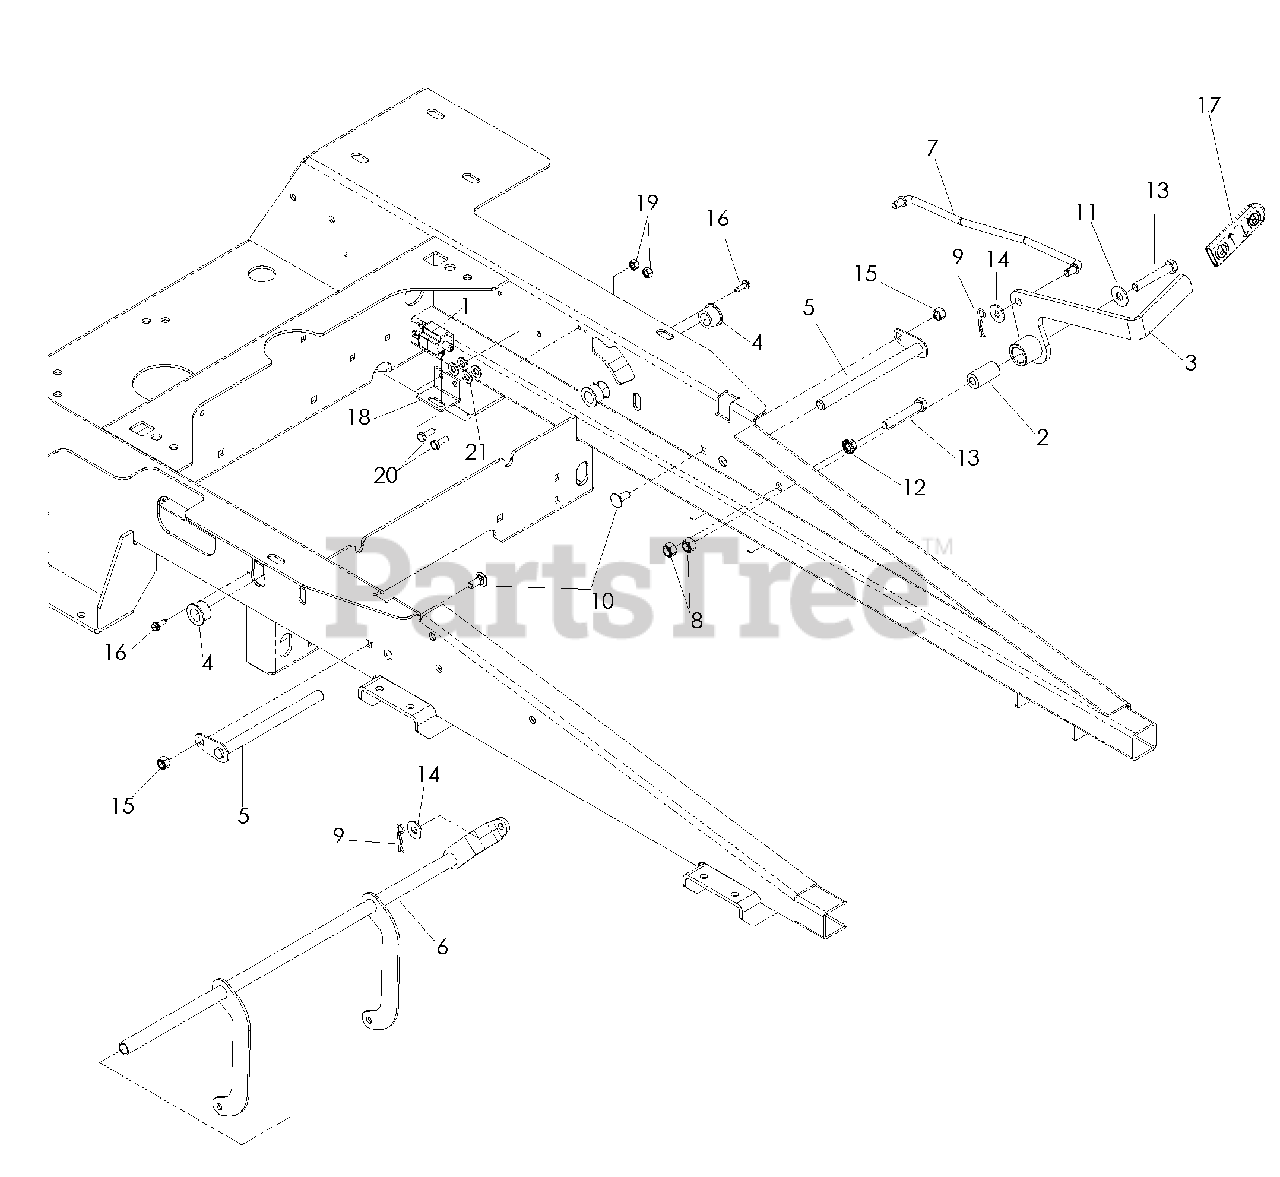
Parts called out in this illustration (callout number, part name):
1	SWITCH, INTERLOCK
3	BRAKE LEVER
4	BUSHING, PLASTIC
5	PIVOT SHAFT
6	BRAKE SHAFT
8	NUT 3/8-16 NYLOC
9	PIN, HAIR .073 x 17/16
10	RHSNB 5/16-18 x 3/4
11	WASHER 3/8
12	NUT 3/8-16 WHIZLK
13	HCS 3/8-16 x 2 1/4
14	WASHER 5/16
15	NUT 5/16-18 NYLOC
16	SCREW #10-24 x 5/8 WSH HD
17	GRIP, PARK BRAKE
18	BRACKET, BRAKE SWITCH
19	NUT 1/4-20 NYLOC
20	HCS 1/4-20 x 3/4
21	WASHER 5/16 SAE
